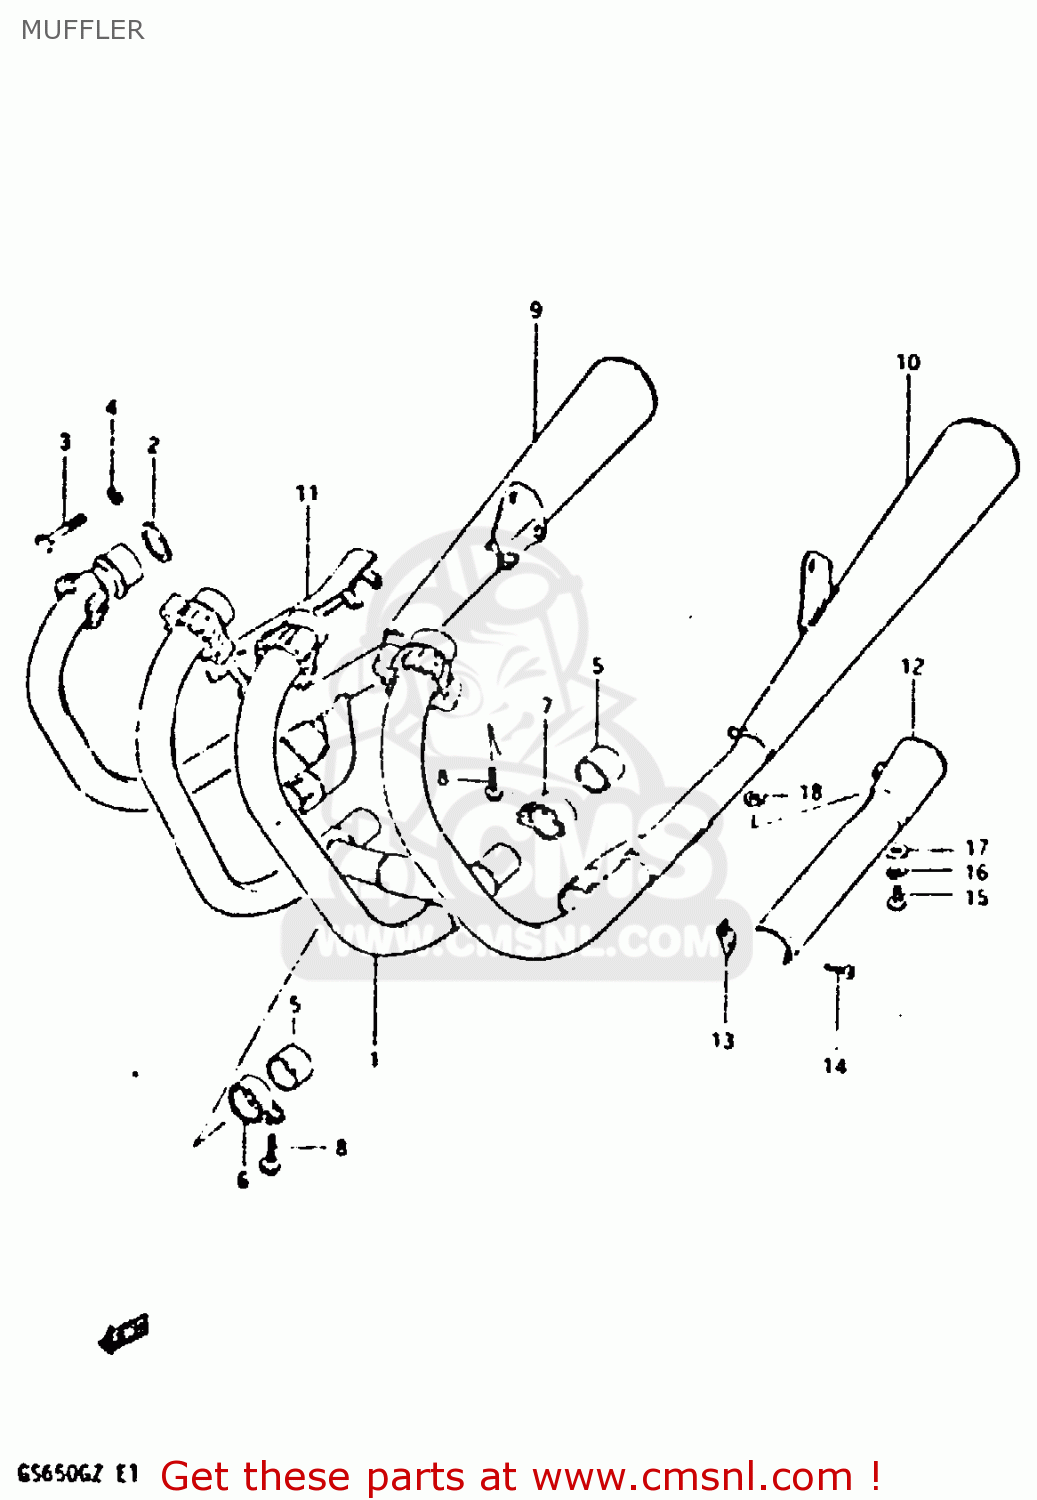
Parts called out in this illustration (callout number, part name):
1	PIPE, EXHAUST CENTER
2	GASKET,EXHAUST PIPE (NAS)
3	BOLT 8X40
4	LOCK WASHER
5	CONNECTOR,MUFFLER
6	CLAMP,MUFFLER CONNECTOR
7	CLAMP,MUFFLER CONNECTOR
8	BOLT
9	MUFFLER, RH
10	MUFFLER, LH
11	COVER,MUFFLER
12	COVER,MUFFLER
13	CLAMP,MUFFLER COVER
14	SCREW 5X20
15	SCREW 6X12
16	LOCK WASHER
17	WASHER
18	GASKET 6.2X12X1.5 (MCA)
